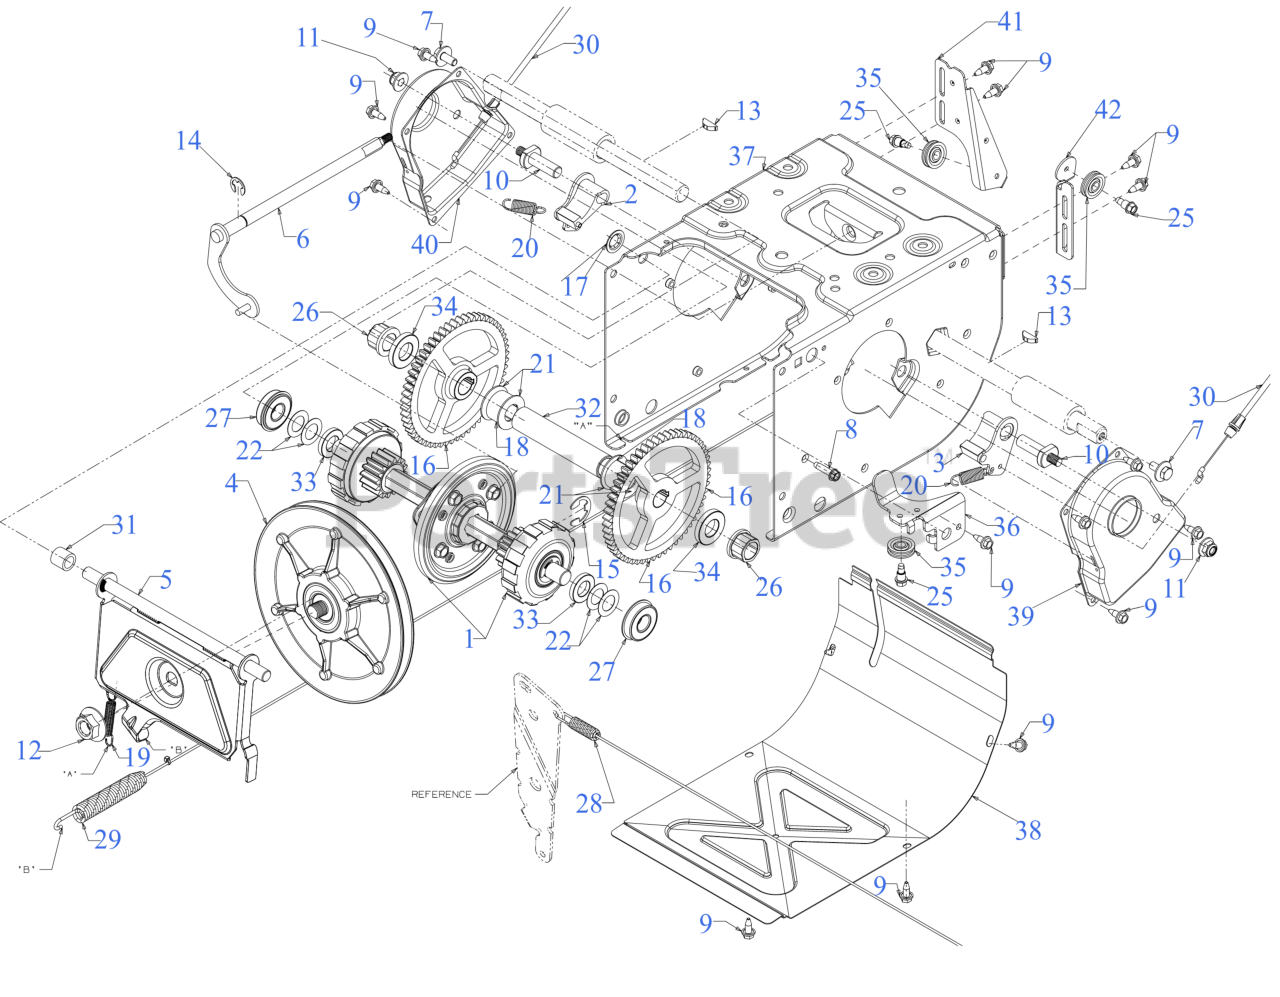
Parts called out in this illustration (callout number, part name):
1	PLANETARY FRICTION WHEEL HEX SHAFT
1	FRICTION WHEEL ASSEMBLY
2	DOGG ASSEMBLY (RH)
3	DOGG ASSEMBLY (LH)
4	FRICTION WHEEL DISC ASSEMBLY
5	FRICTION WHEEL BRACKET (POWDER BLACK)
6	SHIFT ROD ASSEMBLY
7	SCREW 5/16-24 x .750 GR5
8	SCREW 1/4-20 x 1.00
9	SCREW 1/4-20X.625
10	ACTUATOR SHAFT
12	FLANGE NUT 5/8-18
13	KEY 3/16 x 3/4
14	E-RING FOR .500 SHAFT
15	RETAINING RING
18	SPACER: .76ID x .75
19	EXTENSION SPRING
20	EXTENSION SPRING
21	FLAT WASHER
22	FLAT WASHER .67X 1.174X .02
25	SHOULDER SCREW
26	FLANGE BEARING
27	BALL BEARING W/RET
28	AUGER DRIVE CABLE 47.48"
29	WHEEL DRIVE CABLE 44.955"
30	STEERING CABLE
31	SPACER-.513 ID x .703 OD x .69
32	AXLE SUPPORT TUBE
34	AXLE SPACER
35	CABLE GUIDE ROLLER
36	AUGER CABLE BRACKET
37	DRIVE FRAME
41	CABLE GUIDE BRACKET (DRIVE)
42	CABLE GUIDE BRACKET (AUGER)
